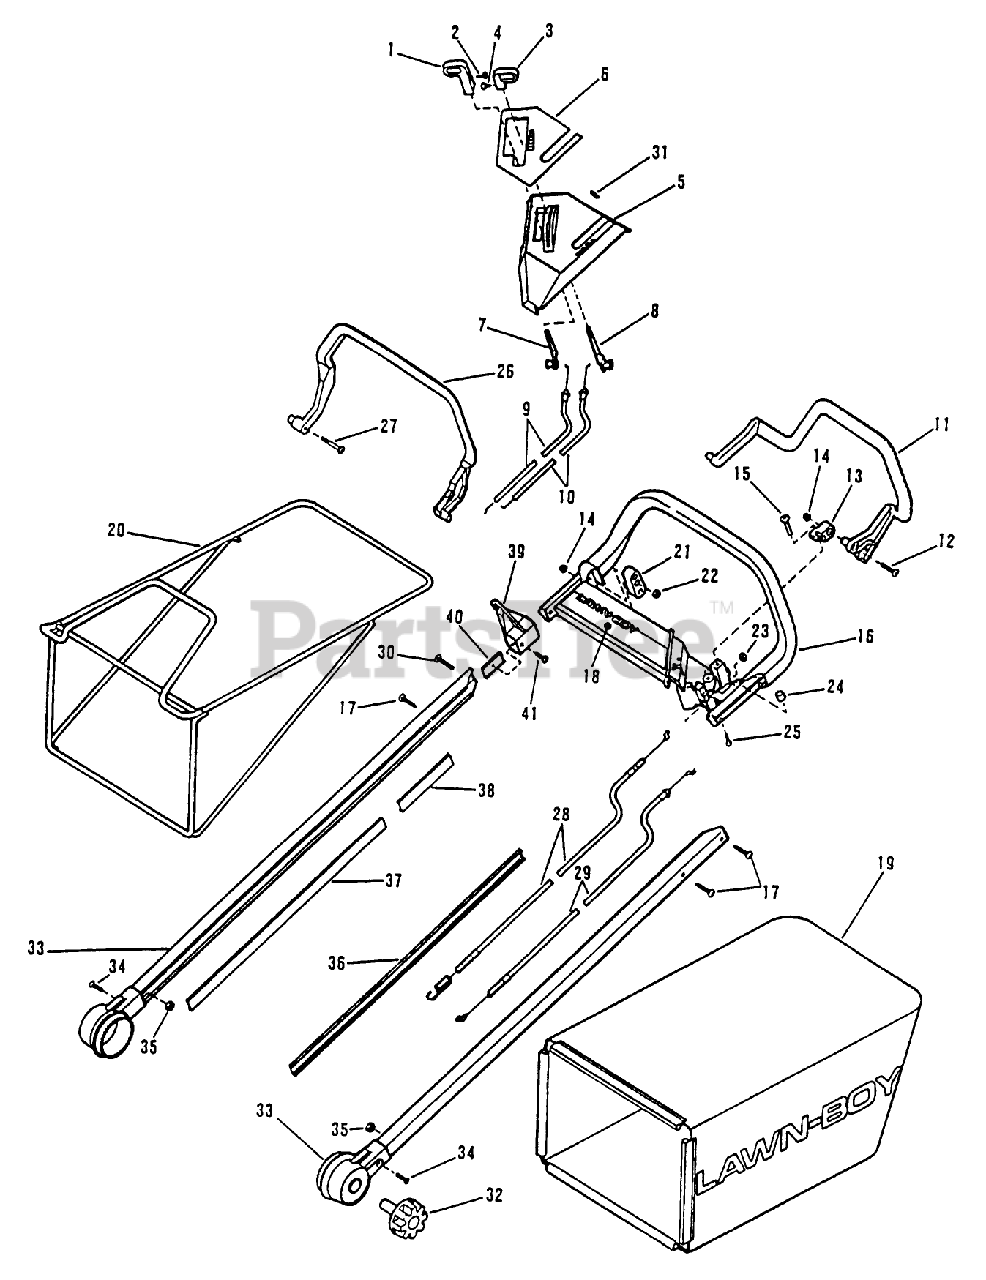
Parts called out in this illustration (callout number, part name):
1	KNOB & SCREW AY
5	UPPER CVR&DECAL AY
9	CABLE AY. WESCON
11	BAIL-S.P. *
13	PIVOT BAIL PL
14	LOCKNUT FLAN
21	BLOCK BAIL PL
22	LOCKNUT E
28	CABLE AY
29	CABLE ASSEMBLY
30	SCREW-TRUSS
32	KNOB-HDLE MT.ASM*B
33	HANDLE SHAFT AY
35	LOCKNUT FLAN
36	INSERT - HANDLE
